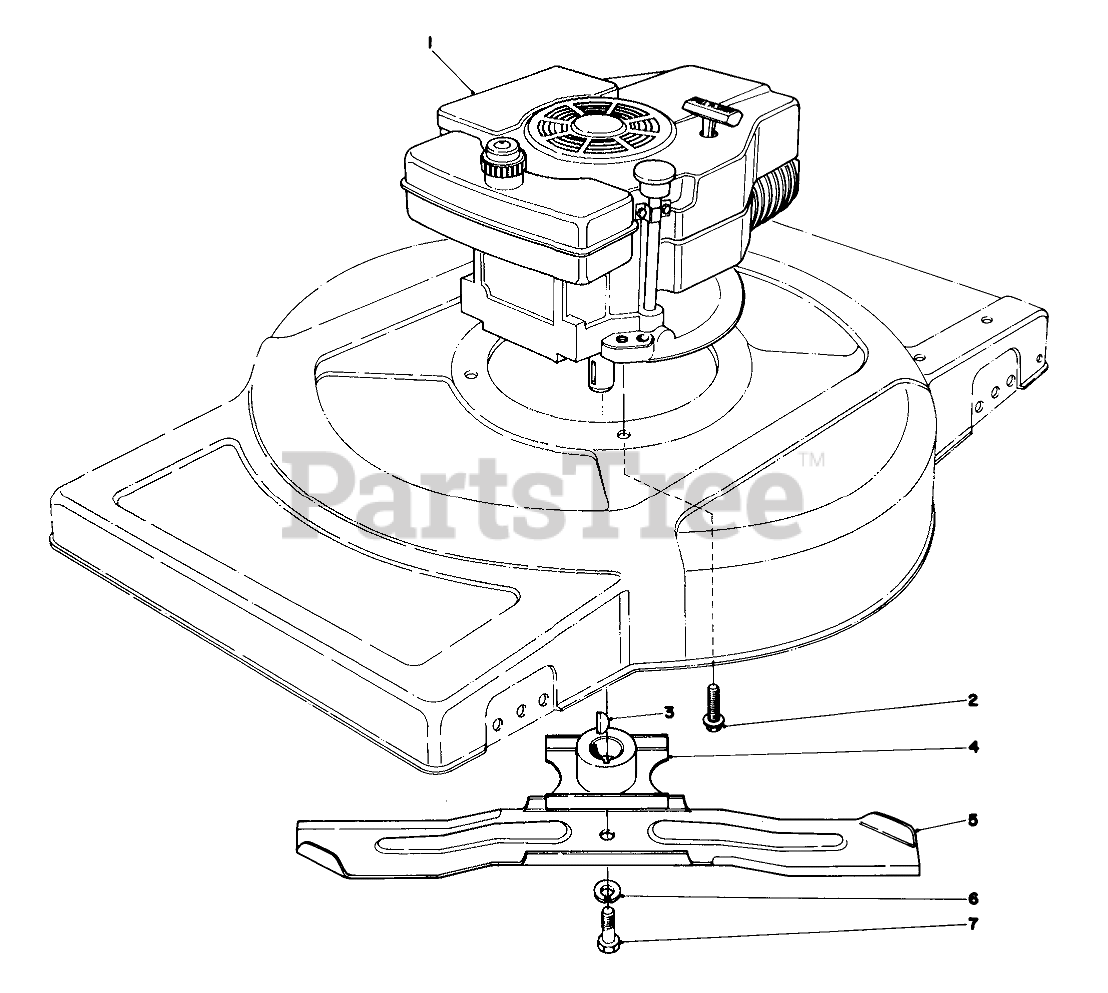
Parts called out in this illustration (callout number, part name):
1	Engine
2	SCREW-HWHTF
3	KEY-WOODRUFF
4	BLADE RETAINER WA(BLACK)
5	Blade
6	WASHER-LOCK
7	BLADE SCREW
